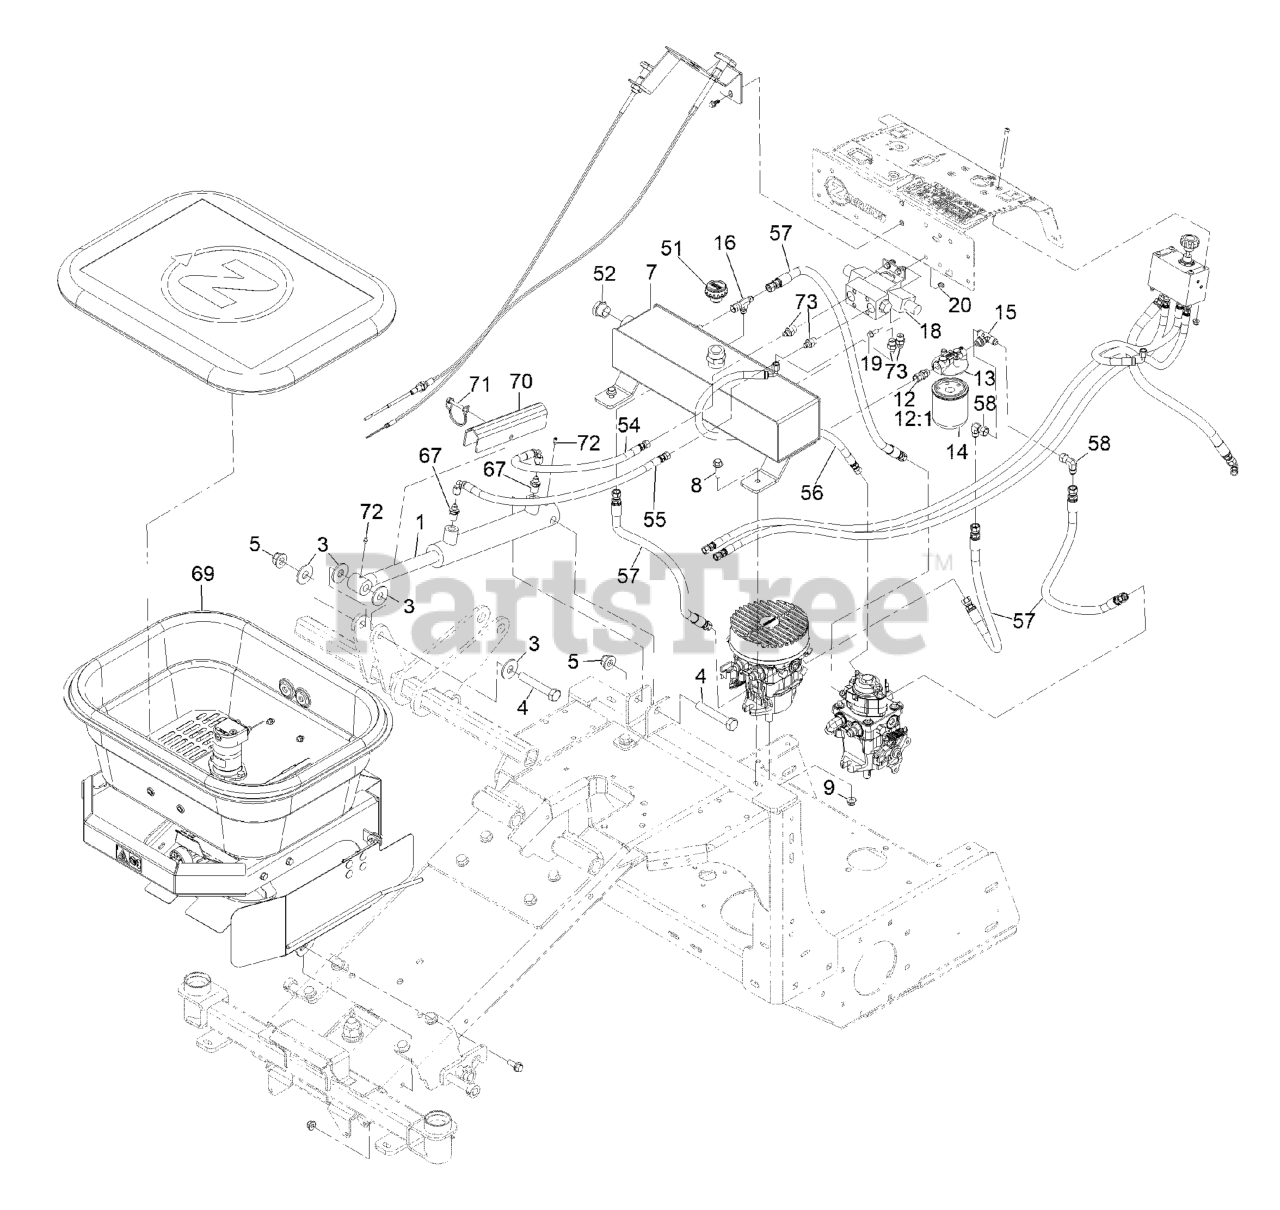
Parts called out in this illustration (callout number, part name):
1	LIFT CYLINDER NEW STYLE 8
3	WASHER-FLAT
4	SCREW-HH
5	Nut-Hex Flg 5/8-11 Nyloc
7	TANK-HYDRAULIC, ZPLUG
8	SCREW-HHF
9	NUT-HF, NI
12	6FJIC SWIVEL-6MORB
12:1	O-RING
13	HEAD-FILTER
14	Filter-Hydraulic
15	TEE-6MJIC-6MJIC-6MORB
16	FITTING-HYD, TEE
18	PARKER ELECTRIC ACTUATED
19	SCREW-HHF
51	HYDRAULIC TANK VENT CAP
52	FLUID SITE WINDOW
54	Hose ASM-HYD HP
55	Hose ASM-HYD HP
56	Hose ASM-HYD HP
57	HOSE-24,3/8,100R6,6FJIC,6
58	ELBOW-SWIVEL, 90 DEG
67	FITTING-STR
70	STOP-CYLINDER
71	PIN-HITCH
72	FITTING-GREASE
